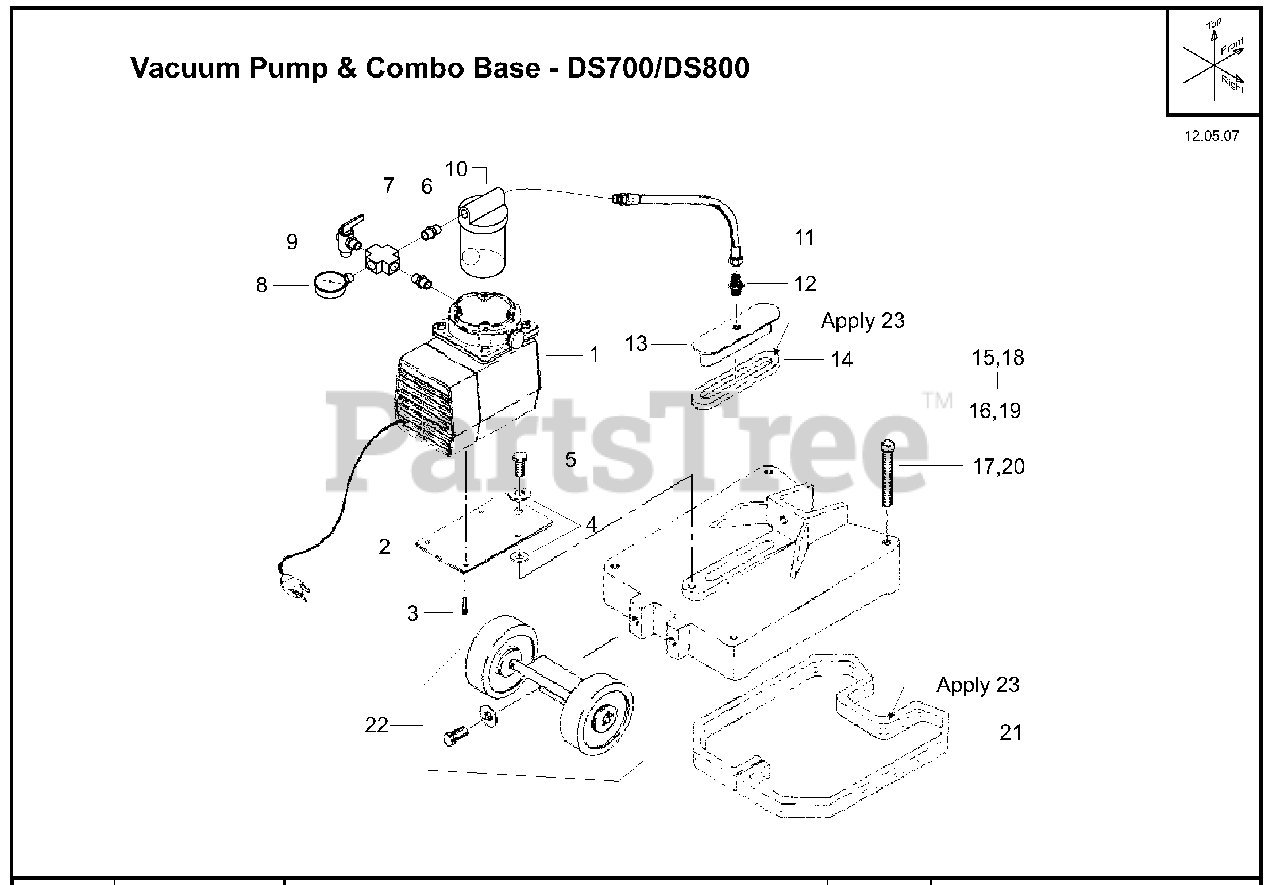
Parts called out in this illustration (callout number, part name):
1	Pump, Vacuum 115V/60/1
2	Bracket, Pump Mounting
3	Capscrew, Soc Hd 10-32 x 3/4"
4	Washer, Flat 1/2" SAE
5	Capscrew, Hex Hd 1/2-13 x 1"
6	Pipe Fit., Hex Nipple 1/4 NPT - Brass
7	Pipe Fit., Female Cross 1/4 NPT - Brass
8	Gauge, Vacuum
9	Valve, Vacuum Release
10	Trap, Water - compl
11	Hose, Vacuum Pump
12	Pipe Fit., Hex Nipple 1/4 NPT w/ 30 Deg Chamfer
14	Gasket, Slot Cap
15	Base, Combo, DS700 - Compl
16	Base, Large, DS700 - Husq Orange
17	Capscrew, Sq Hd 1/2-13 x 4"
18	Base, Combo, DS800 - Compl
19	Base, Large, DS800 - Husq Orange
20	Capscrew, Sq Hd 3/4-10 x 4"
21	Gasket, Combination Base
22	Axle & Wheels - compl
23	Adhesive, Tube - 5 OZ
